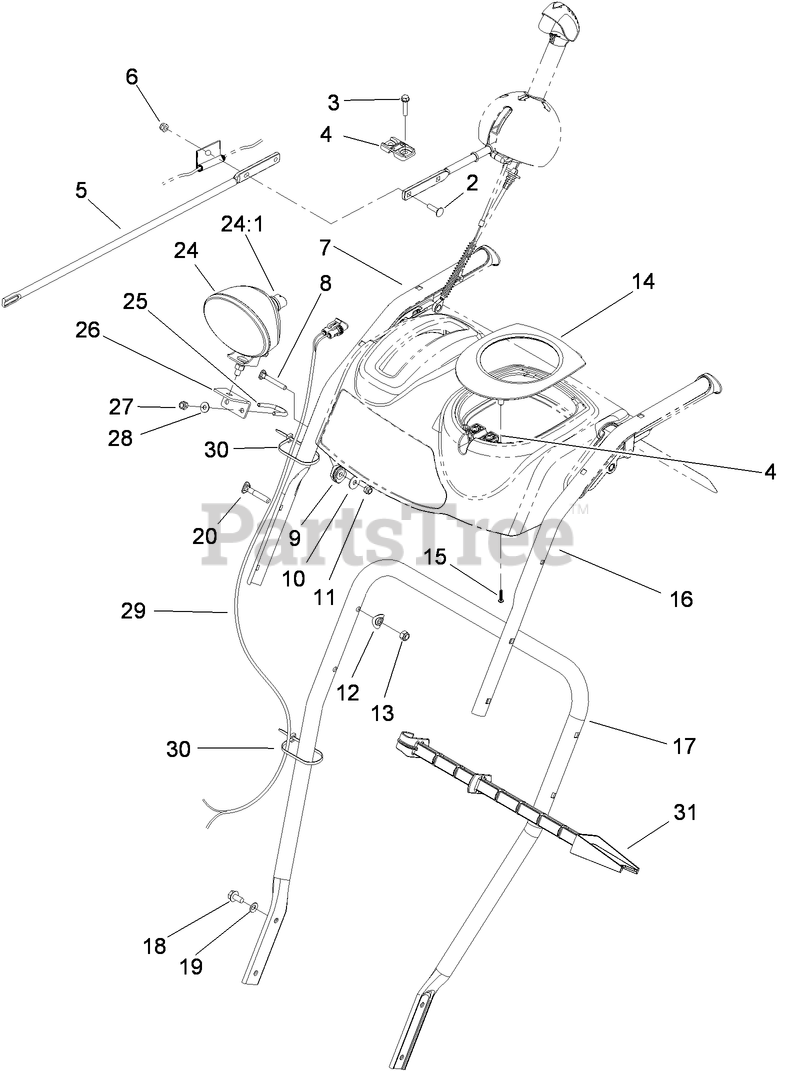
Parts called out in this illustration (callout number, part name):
2	SCREW-CARR
3	SCREW-PLASTITE
4	SUPPORT-ROD
5	ROD-CHUTE, FRONT
6	NUT-LOCK, NI
7	HANDLE-UPPER, RH
8	SCREW
9	CLAMP-CABLE
10	WASHER-PLAIN
11	NUT-LOCK, NI
12	WASHER
13	NUT-LOCK, NI
14	COVER-PANEL, CONTROL
15	SCREW-PPH
17	HANDLE-LOWER
18	SCREW-HWHTF
19	WASHER-BELLEVILLE
20	SCREW-HANDLE
24	HEADLAMP ASM
24:1	LAMP-12 VOLT
26	BRACKET-LIGHT
27	NUT-LOCK, NI
28	WASHER-FLAT
29	HARNESS-WIRE
30	TIE-CABLE
31	STICK-CLEANOUT
